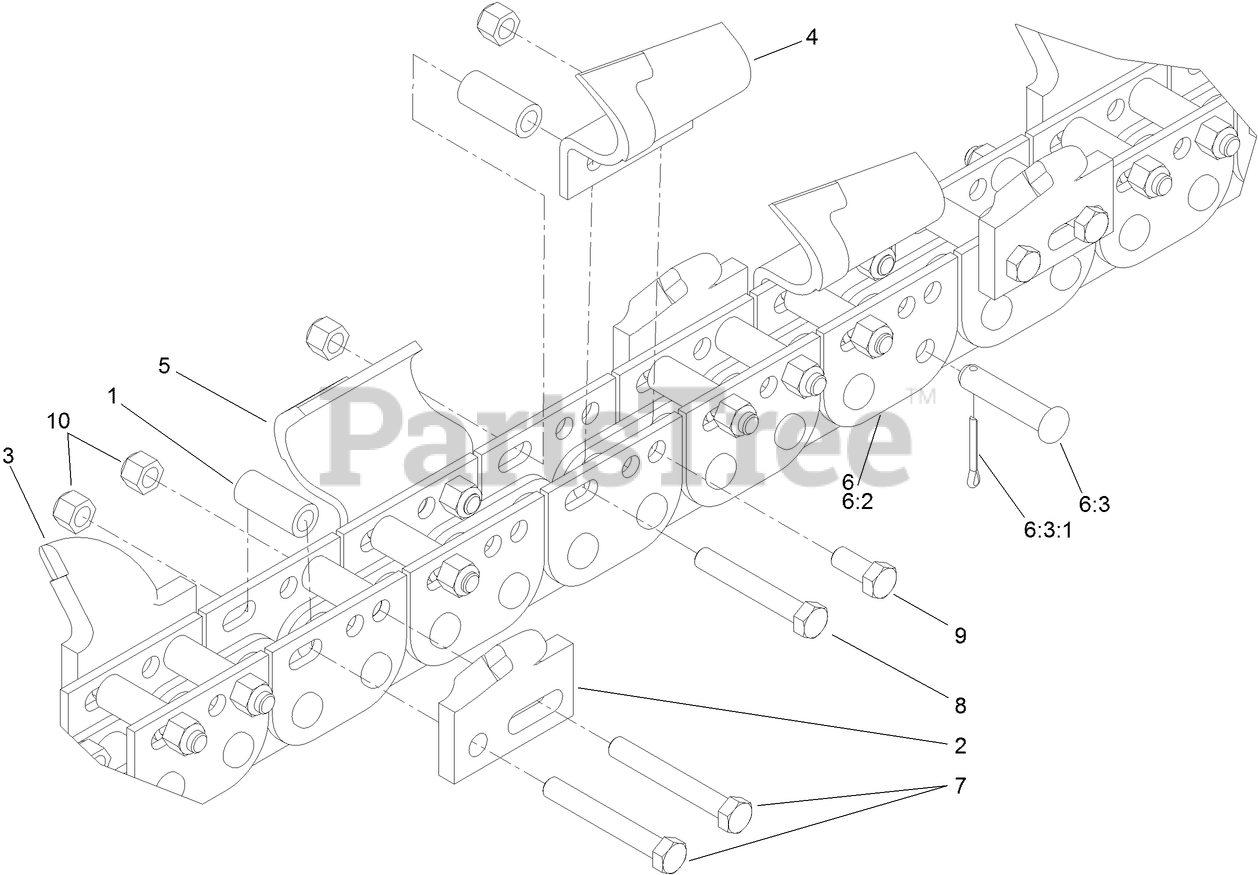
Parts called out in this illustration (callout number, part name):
1	SPACER-TUBE
2	TOOTH- ROCK, LH
3	TOOTH-ROCK, RH
4	TOOTH-SOIL, LH
5	TOOTH-SOIL, RH
6	CHAIN-BARE, 24 STATION
6:2	LINK REPAIR KIT
6:3	PIN-CONNECTING (61MM)
6:3:1	PIN-COTTER
7	SCREW-HH
8	SCREW-HH
10	NUT-HEX
